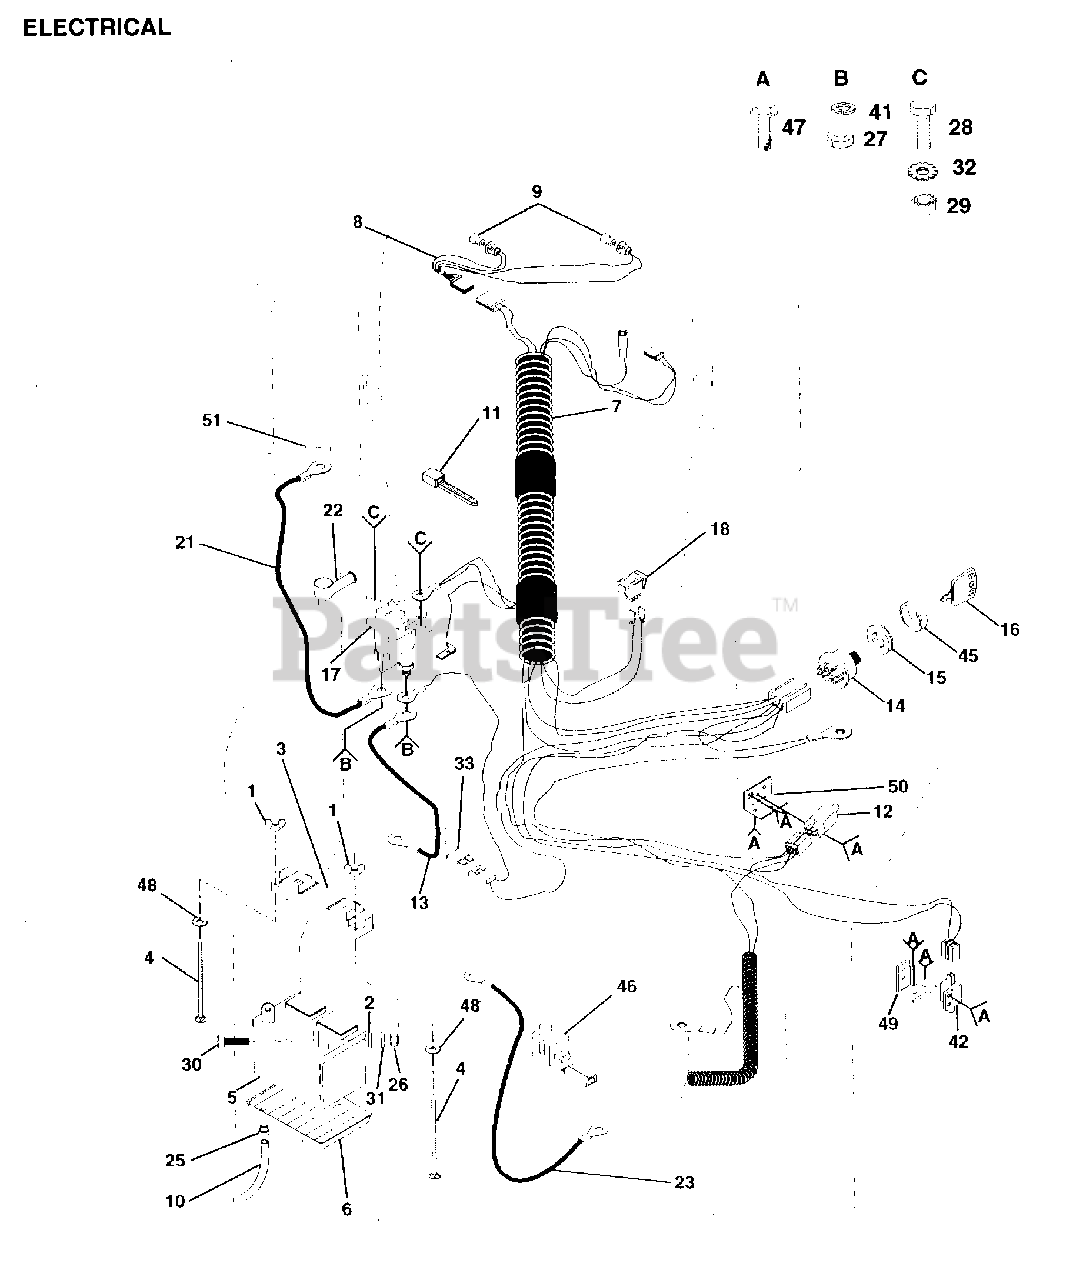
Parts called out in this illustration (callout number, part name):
2	WASHER
4	BOLT
6	"TRAY T, BATTERY"
7	HARNESS.IGN. B&S
10	"DRAIN TU T, BATT"
11	WIRE TIE
12	SWITCH INTERLOCKT
13	CABLE-BATTERY T
15	NUT IGNITION
16	KEY
18	SWITCH LT
21	"CABLE T, BATTERY"
23	CABLE T
25	HOSE CLAMP T
26	LOCKWASHER
27	NUT
28	BOLT
29	NUT
30	BOLT LT
33	FUSE HYT
42	SWITCH-INTER. GT
46	SWITCH SEAT
47	SCREW
48	WASHER.3/4X1X18GA
49	BRACKET LT
50	SWITCH BRACKET
51	LOCKWASHER
